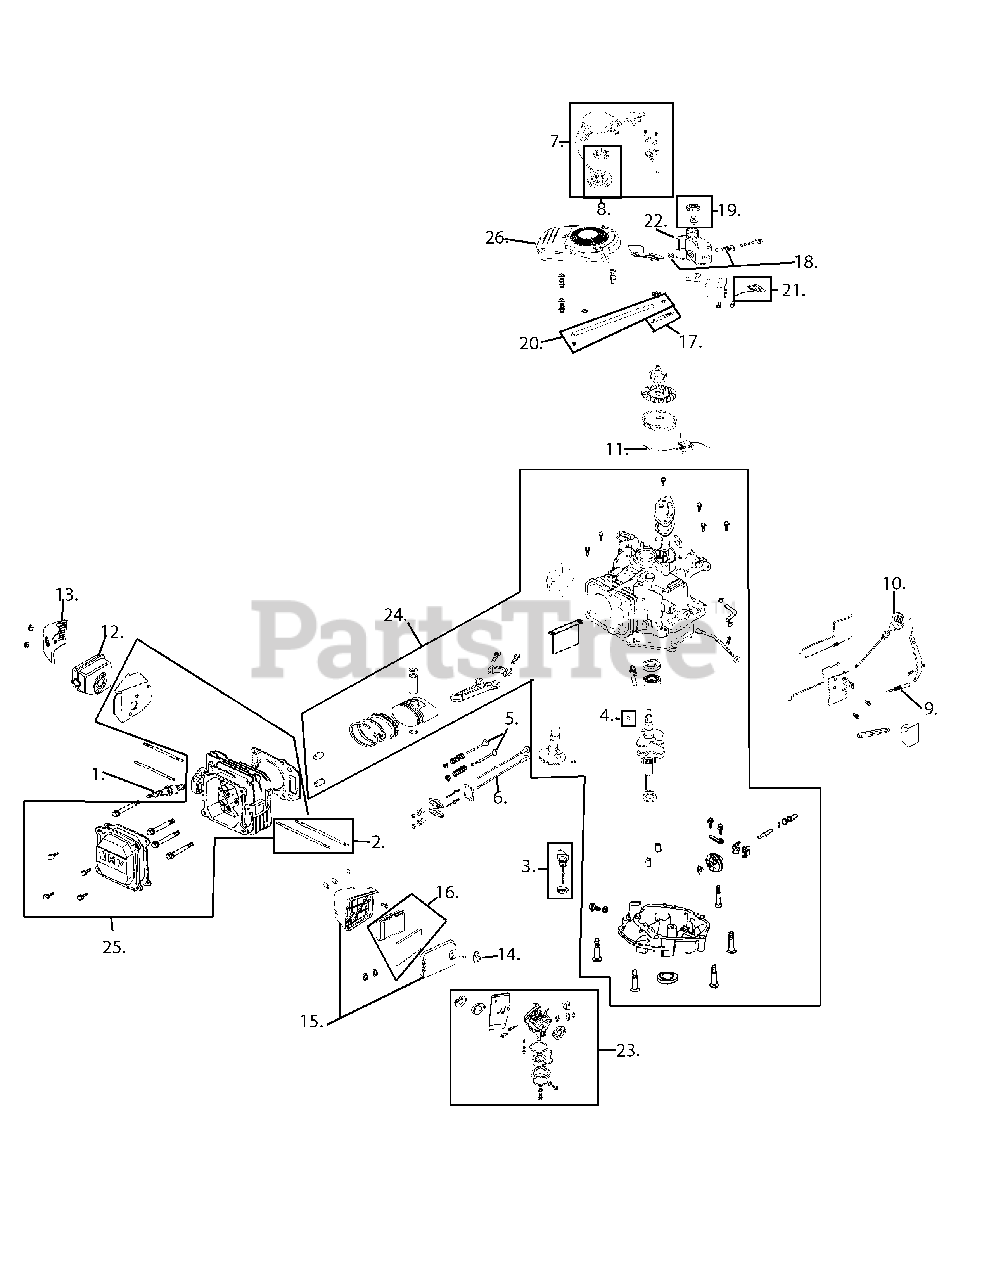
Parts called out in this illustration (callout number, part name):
1	Spark Plug
2	Muffler Stud Assembly
3	Dipstick Assembly
4	Flywheel Key
5	Valve Kit
6	Push Rod Kit
7	Recoil Starter Assembly
8	Recoil Spring & Pulley Assembly
9	Governor Return Spring
10	Choke Control Knob
11	Ignition Coil
12	Muffler Assembly
13	Muffler Shield
14	Air Cleaner Thumb Screw
15	Air Cleaner Housing Assembly Complete
16	Air Cleaner Kit
17	Fuel Filter
18	Rubber Fuel Tank Mounting Washer
19	Fuel Cap Assembly
20	Fuel Line Kit
21	Ignition Switch
22	Fuel Tank
23	Carburetor Assembly
24	Short Block Assembly
25	Cylinder Head Assembly
26	Engine Shroud - Black
